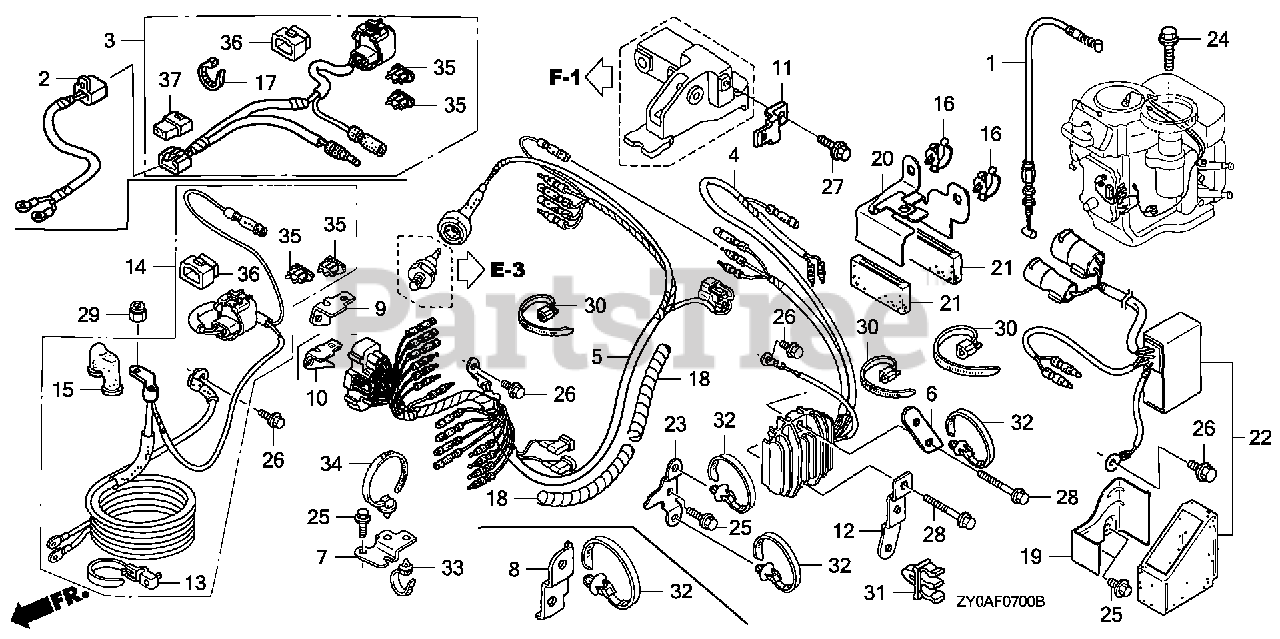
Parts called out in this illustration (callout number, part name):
1	CABLE, NEUTRAL STARTING
4	RECTIFIER ASSY., REGULATOR
5	WIRE HARNESS ASSY. (SELF STARTER)
6	BRACKET, CLIP F
7	BRACKET, STARTER CABLE
10	BRACKET, FUSE CASE (PT)
12	BRACKET, E-CLIP
13	BAND, WIRE
14	CABLE ASSY., STARTER (PT)
15	COVER, MAGNETIC SWITCH TERMINAL
16	CLAMP, WIRE
18	TUBE, SPIRAL A
19	BRACKET, RELAY (PT)
20	BRACKET, CONNECTOR A
21	GROMMET, CONNECTOR
22	RELAY ASSY., POWER TILT
23	BRACKET, HARNESS CLIP
24	BOLT, FLANGE (6X20)
25	BOLT, FLANGE (6X14) (CT200)
26	BOLT, FLANGE (6X12)
28	BOLT, FLANGE (6X26) (CT200)
29	NUT, LOCK (6MM)
30	TIE, CABLE
31	CLIP, FUEL TUBE
32	CLIP, HARNESS BAND (151.5MM) (NATURAL)
33	BAND, WIRE HARNESS (123.5MM) (BLUE)
34	BAND, WIRE HARNESS (93.5MM) (WHITE)
35	FUSE, BLADE (20A)
36	COVER ASSY., FUSE (20A)
